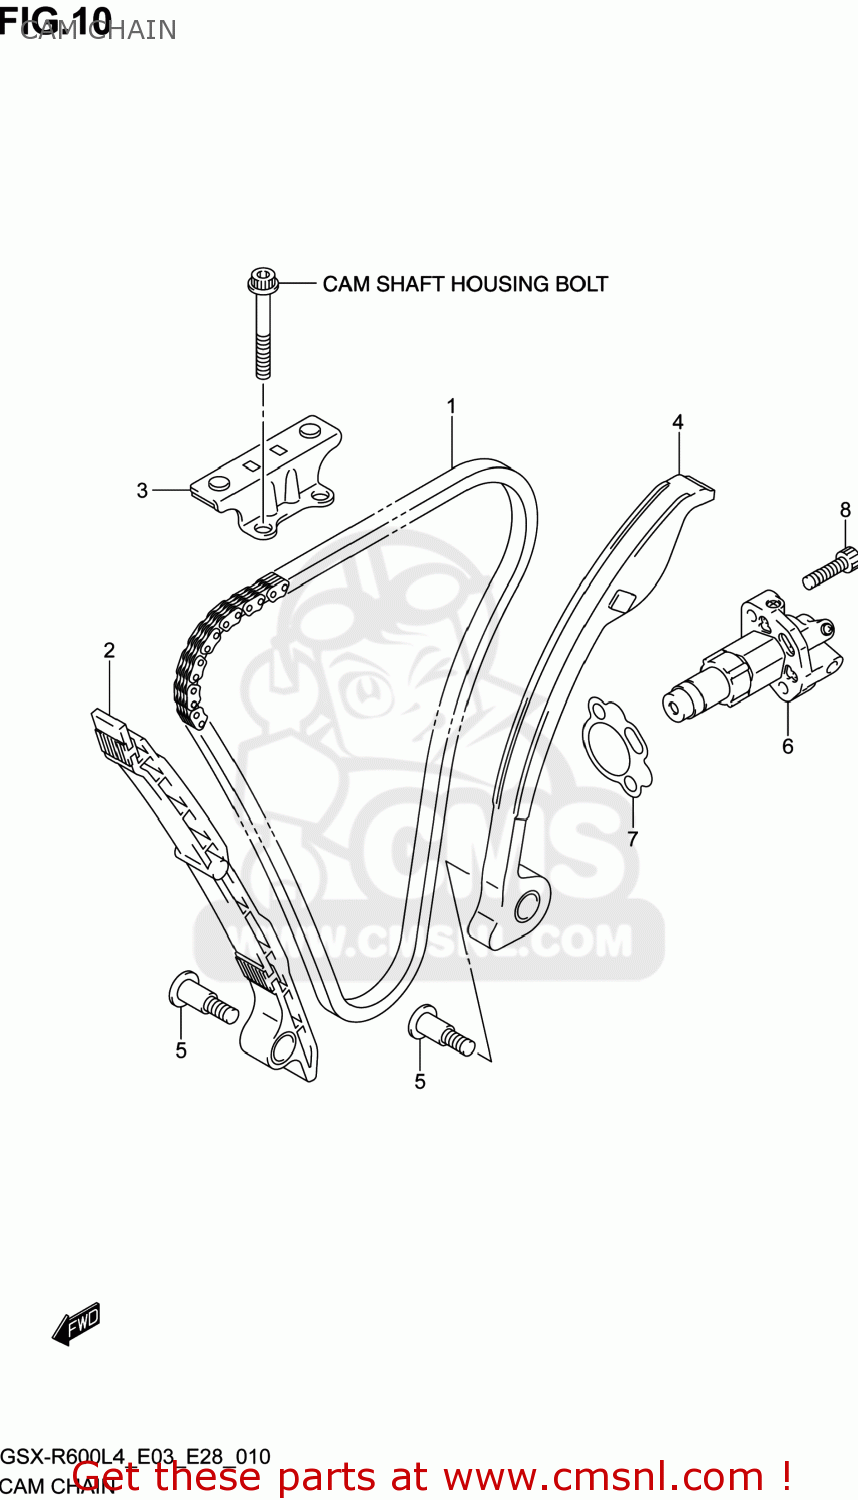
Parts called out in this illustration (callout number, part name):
1	CHAIN,CAMSHAFT DRIVE
2	GUIDE,CAM CHAIN NO.1
3	GUIDE,CAM CHAIN NO.2
4	TENSIONER,CAM CHAIN
5	BOLT,CAM CHAIN TENSIONER
6	ADJUSTER ASSY,TENSIONER
7	GASKET,TENSIONER ADJUSTER (NAS)
8	BOLT
